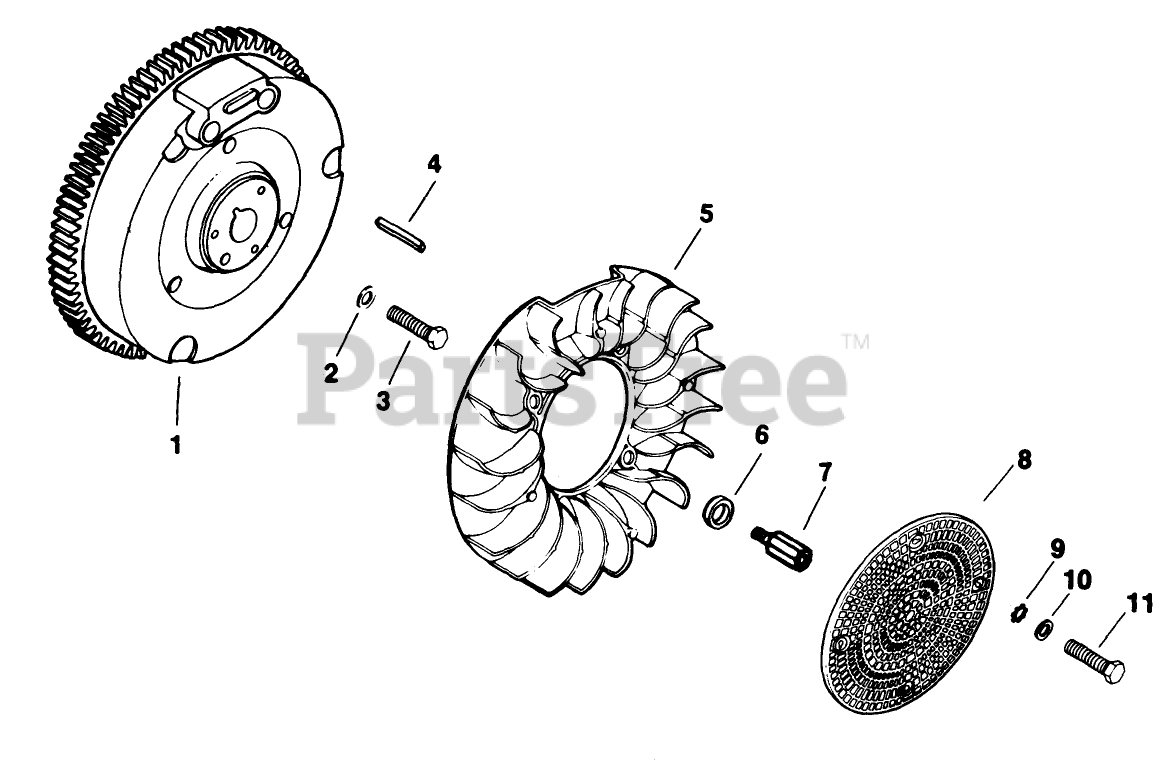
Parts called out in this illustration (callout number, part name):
1	Flywheel
2	Washer-Flat
3	Screw-H.C.
4	Key
8	Screen-Grass
9	Washer-Lock
10	Washer
11	Screw-T.H.
